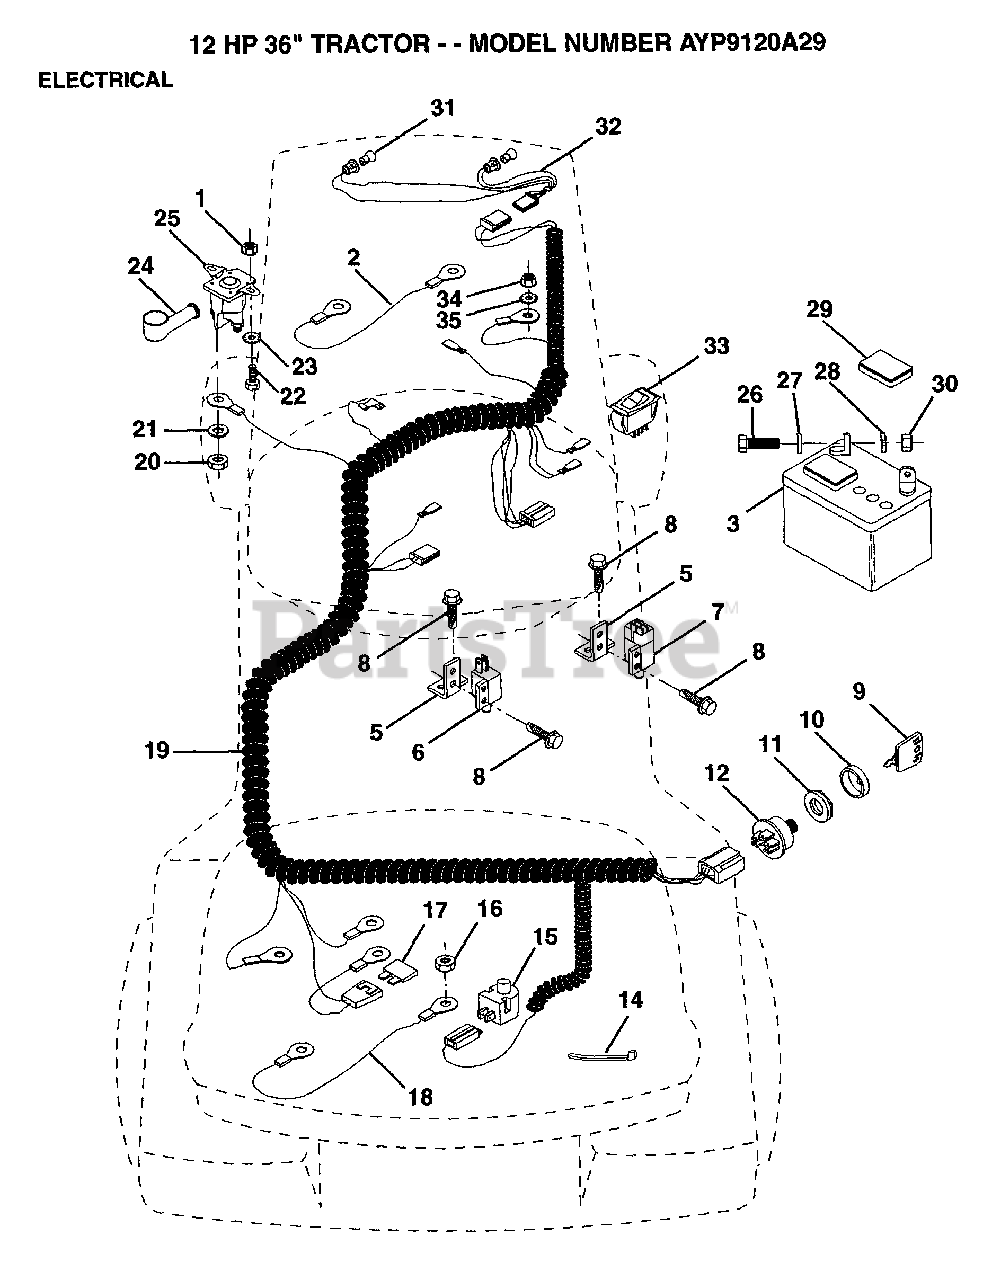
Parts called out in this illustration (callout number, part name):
1	NUT
2	CABLE ASM.
5	BRACKET LT
6	SWITCH-INTER. GT
7	SWITCH INTERLOCKT
8	SCREW
9	KEY
11	NUT IGNITION
14	WIRE TIE
15	SWITCH SEAT
17	FUSE HYT
18	CABLE ASSY
20	NUT
22	BOLT
26	BOLT LT
27	WASHER
28	LOCKWASHER
29	"CAP,BATTERY "
33	SWITCH LT
34	NUT
35	LOCKWASHER
